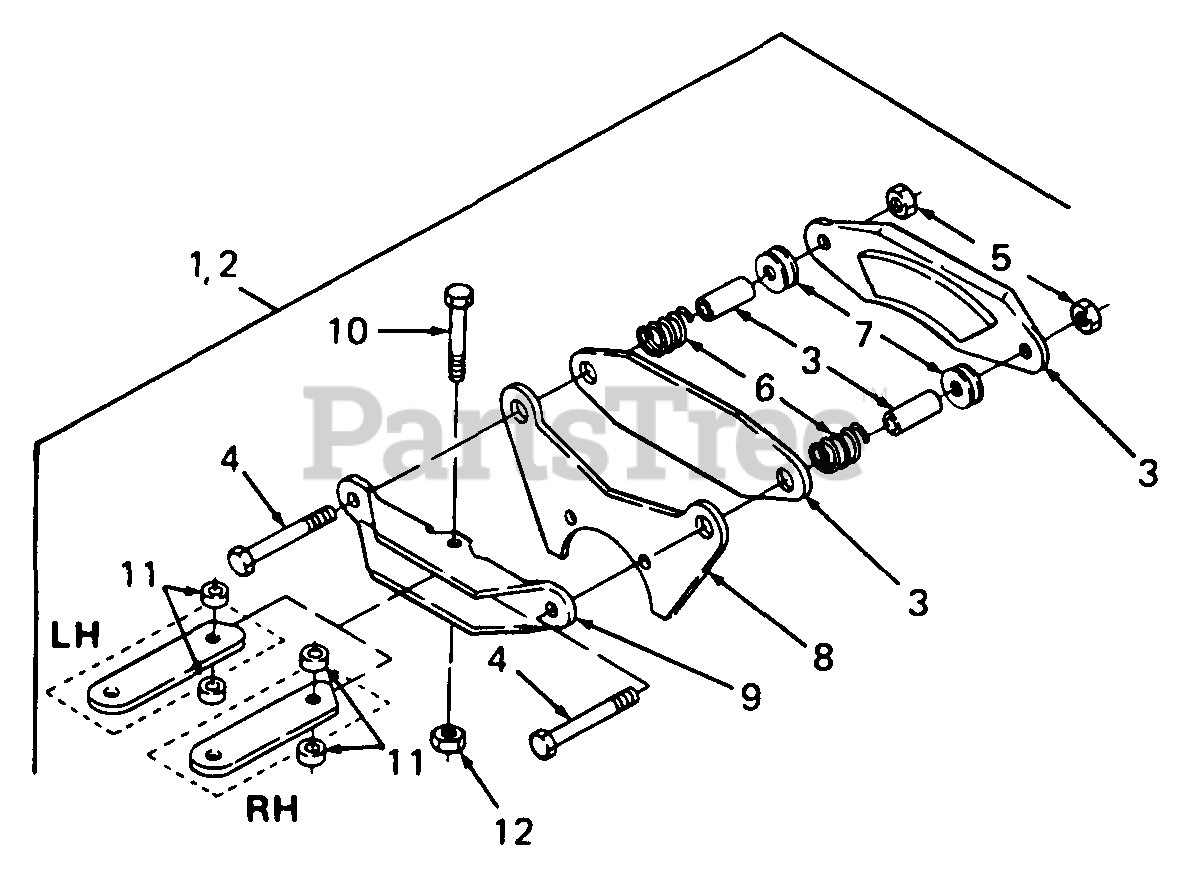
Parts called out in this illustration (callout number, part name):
1	Brake Kit, RH Caliper
2	Brake Kit, LH Caliper
3	Puck Kit, Brake
4	Screw, Hex Cap, 3/8-24 x 2.50 Lg GR5
5	Nut, Hex Lock, 3/8-24 GR5
6	Spring, Compression
7	Washer, Flat, .390 x 1.0 x .030 Thk HDN
8	Bracket, Brake Mounting
9	Bracket Assy, Actuator
10	Screw, Shoulder
12	Nut, Hex Top Lock, 1/4-20
